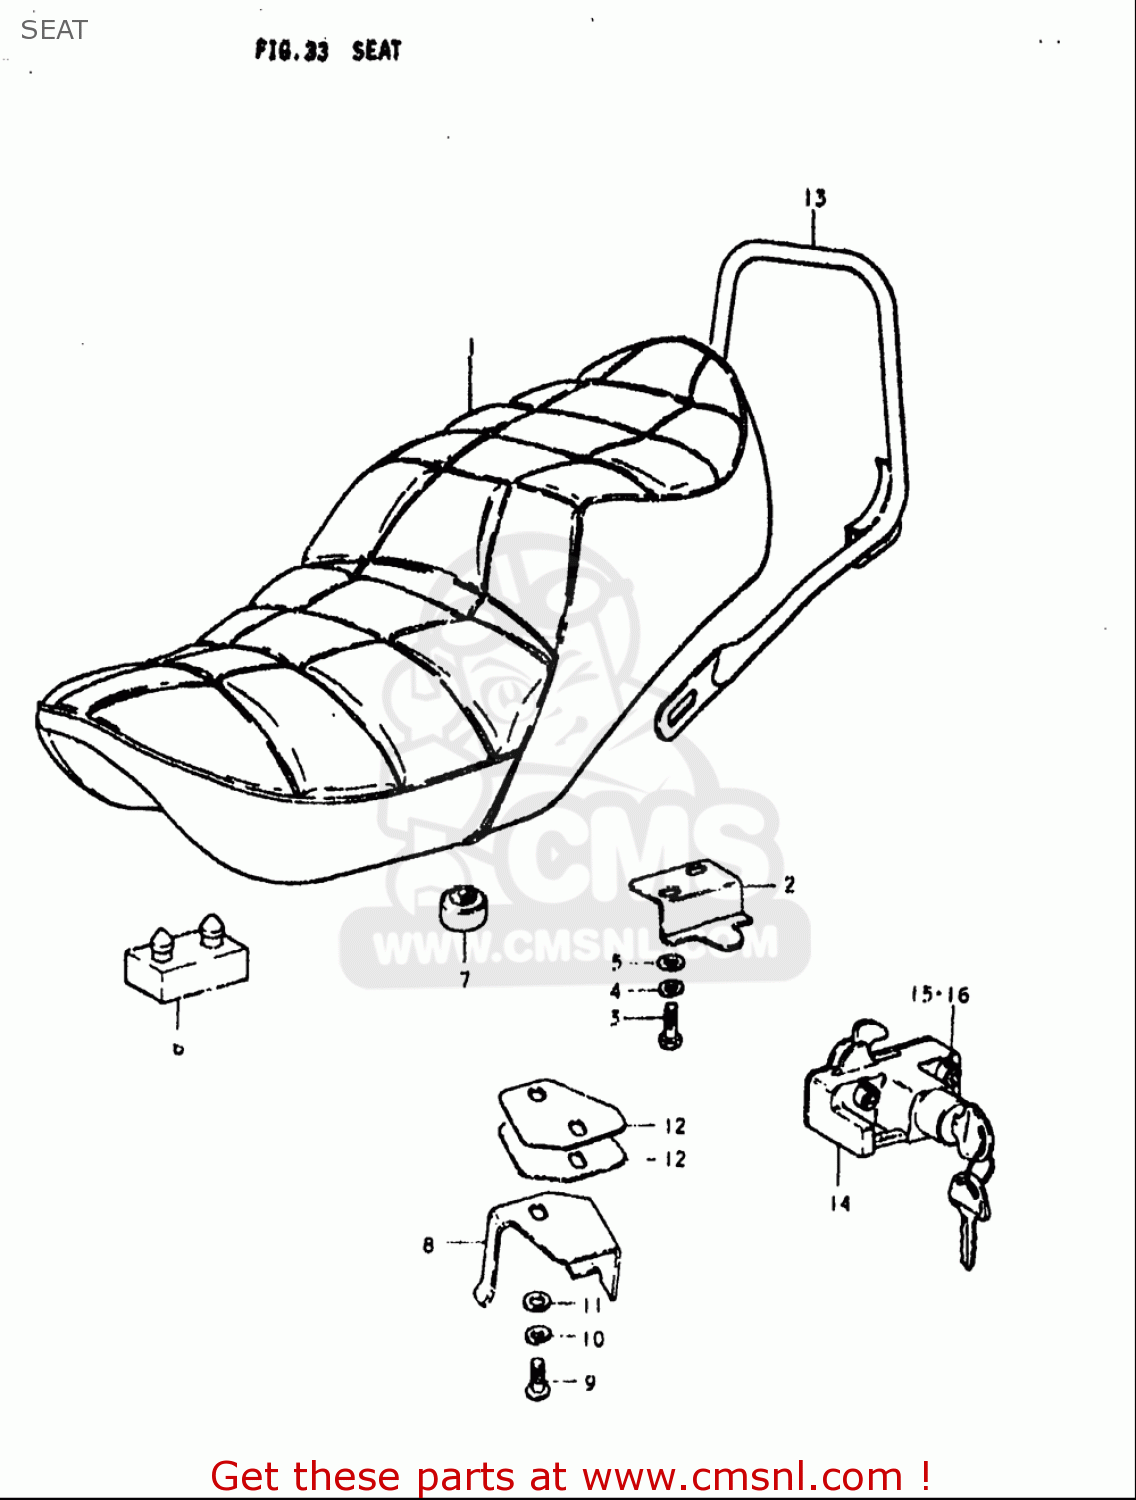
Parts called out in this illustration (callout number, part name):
2	BRACKET
3	BOLT
4	WASHER,LOCK
5	WASHER
6	CUSHION
7	CUSHION
9	BOLT
10	WASHER,LOCK
11	WASHER
16	WASHER,LOCK
